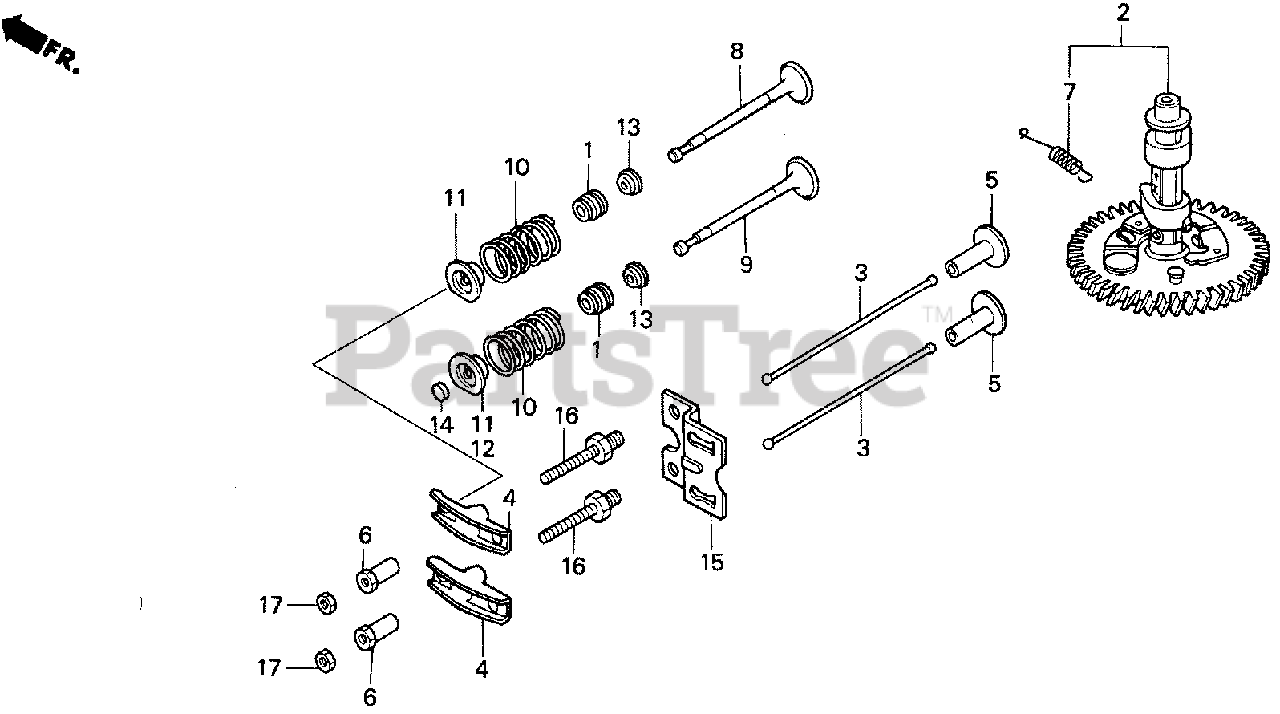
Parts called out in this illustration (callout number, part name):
1	SEAL, VALVE STEM
2	CAMSHAFT
2	CAMSHAFT ASSY.
3	ROD, PUSH
4	ARM, VALVE ROCKER
5	LIFTER, VALVE
6	PIVOT, ROCKER ARM
7	SPRING, WEIGHT RETURN
8	VALVE, IN.
9	VALVE, EX.
10	SPRING, VALVE
11	RETAINER, IN. VALVE SPRING
12	RETAINER, EX. VALVE SPRING
13	SEAT, VALVE SPRING
14	ROTATOR, VALVE
15	GUIDE, PUSH ROD
16	BOLT, PIVOT (8MM)
17	NUT, PIVOT ADJ.
